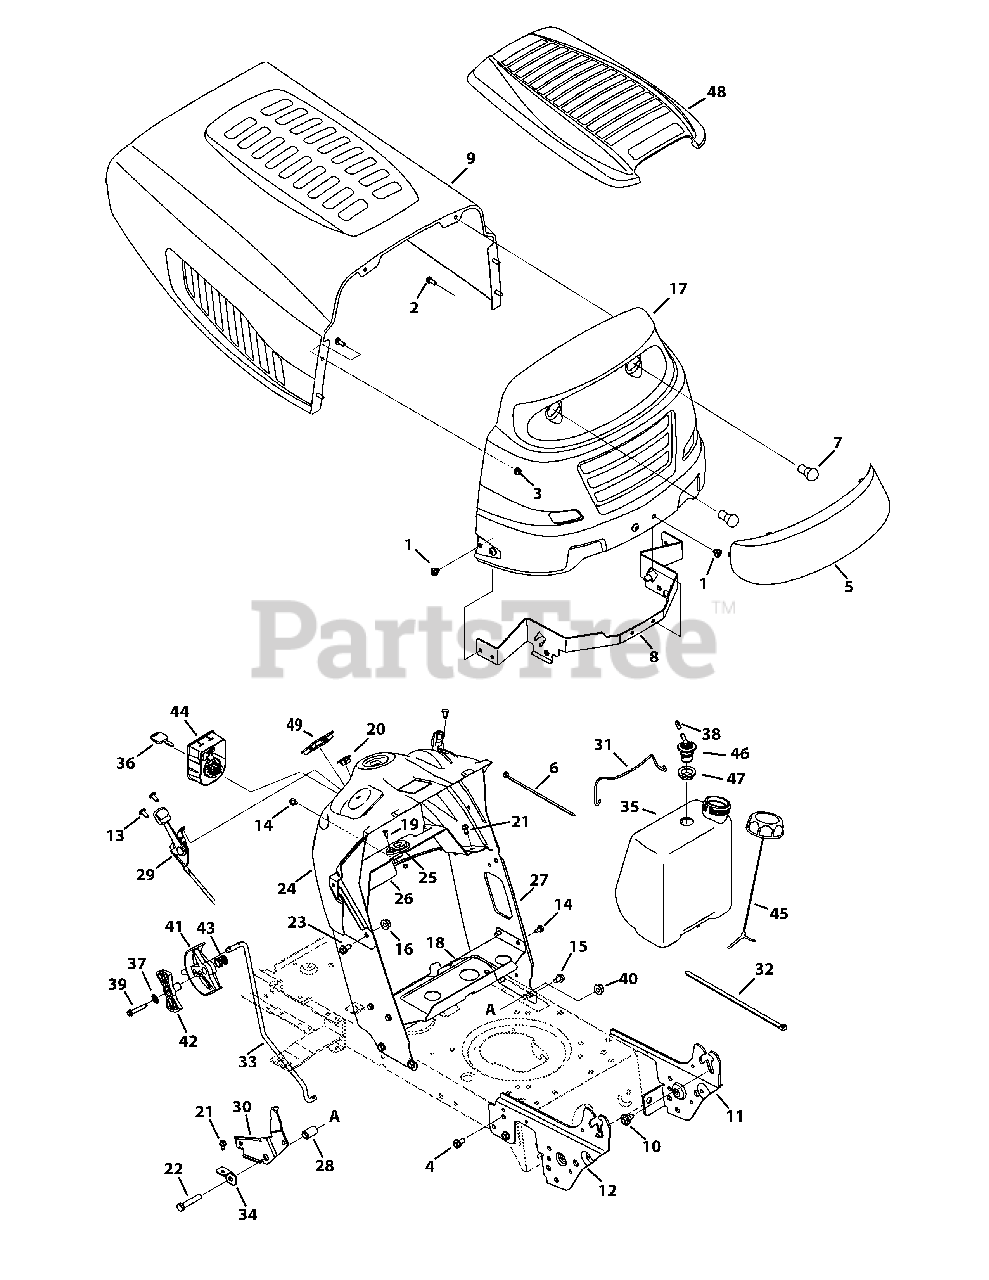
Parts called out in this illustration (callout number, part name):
1	Screw, 5/16-18 x .375
2	Hex Screw, 1/4-20 x .620
3	Flangelock Nut, 1/4-20
4	Screw, 5/16-18 x .750
5	Grill Lens
6	Cable Tie
8	Hood Pivot Bracket
10	Shoulder Screw, 5/16-18 x .43 x .29
11	Left Support Pivot Bracket
12	Right Support Pivot Bracket
13	Screw, 1/4-20 x .500
14	Screw, 1/4-20 x .500
15	Screw, 5/16-18 x .625
16	Flangelock Nut, 5/16-18
19	Screw, #10-16 x .500
20	Choke Plug
21	Tap Screw, 1/4-20, 0.625
22	Hex Screw, 3/8-16 x 2.0
23	Hex Screw, 5/16-18 x .625
24	Dash, Upper
25	Bearing, .628 ID x 1.36
26	Bracket, Steering Support
27	Dash, Lower
28	Flange Spacer, .390 x .671 x 1.095
29	Throttle/Choke Cable
30	Transmission Speed Latch, RMC
31	Battery Assembly Rod
32	Cable Tie
33	Speed Control Rod
34	Speed Latch Tab
35	1.36 Gallon Fuel Tank
36	Key, Assembly
37	Lock Washer, 1/4
38	Hose Vent, 3/16 EPA
39	Hex Washer Screw, 1/4-20 x 1.50
40	Flangelock Nut, 3/8-16
41	Shift Lever
42	Index Control
43	Compr. Spring, .72 OD x .78
44	Key Switch Module
45	Fuel Cap, 2.25"
46	Rollover Valve
47	Rubber Grommet, 23 x 3.55
48	Hood cover
49	Ammeter Plug
